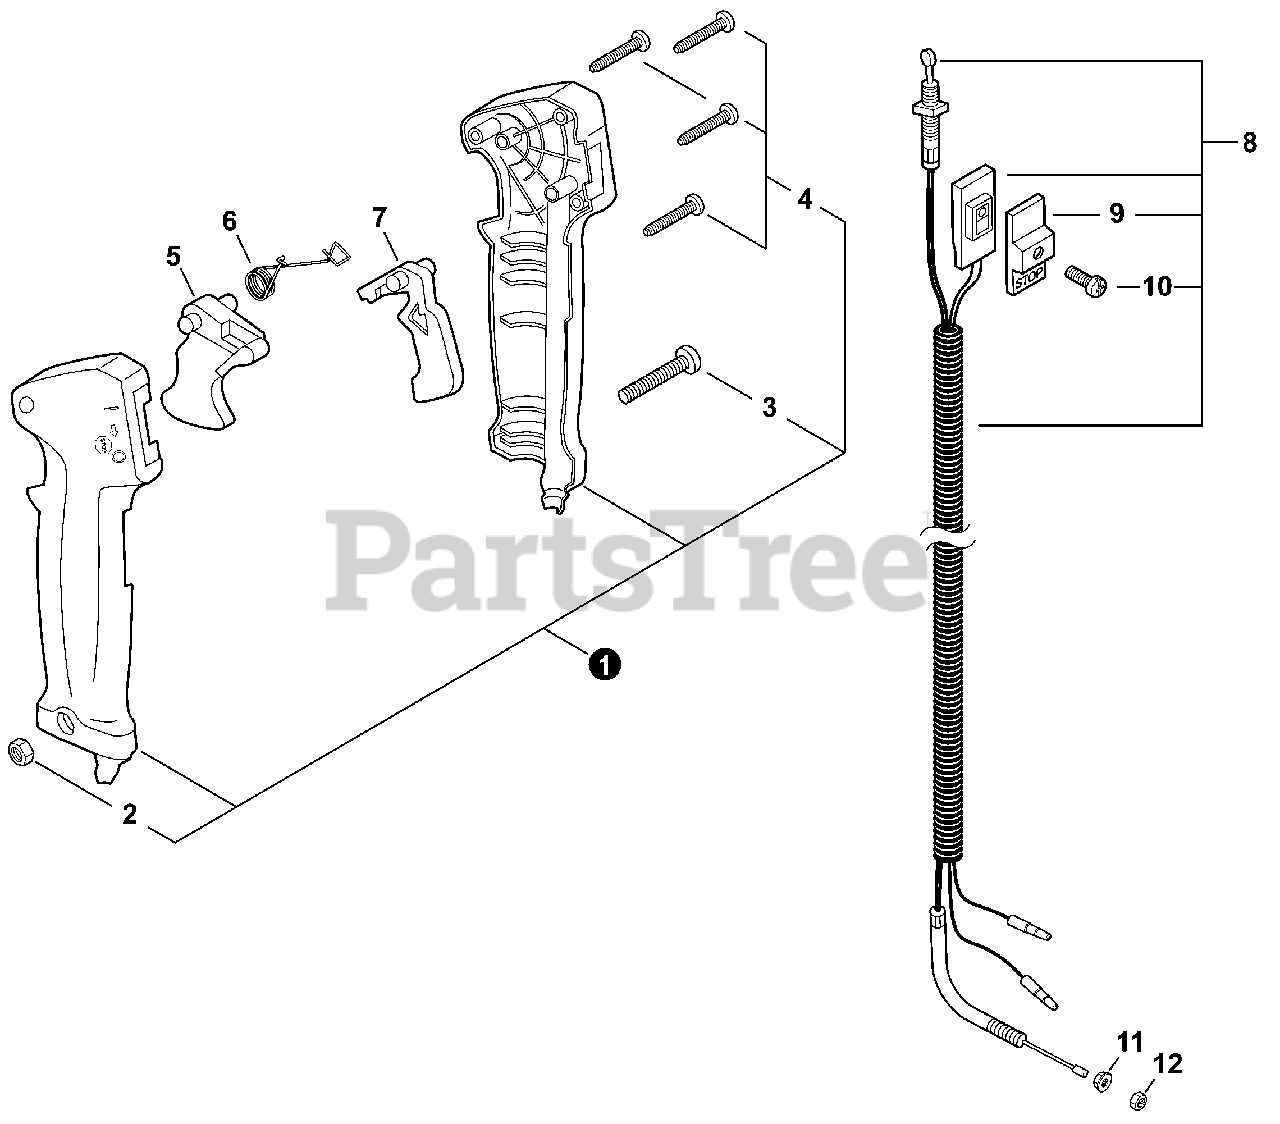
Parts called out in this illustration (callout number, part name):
1	CONTROL HANDLE KIT
2	NUT M5
3	SCREW 5×30
4	SCREW 3×25
5	TRIGGER, THROTTLE
6	SPRING, TORSION
7	LOCKOUT, THROTTLE
8	CABLE ASSY, CONTROL
9	KNOB, SWITCH - ORANGE
10	SCREW 3×10
11	NUT, FLANGE M6
